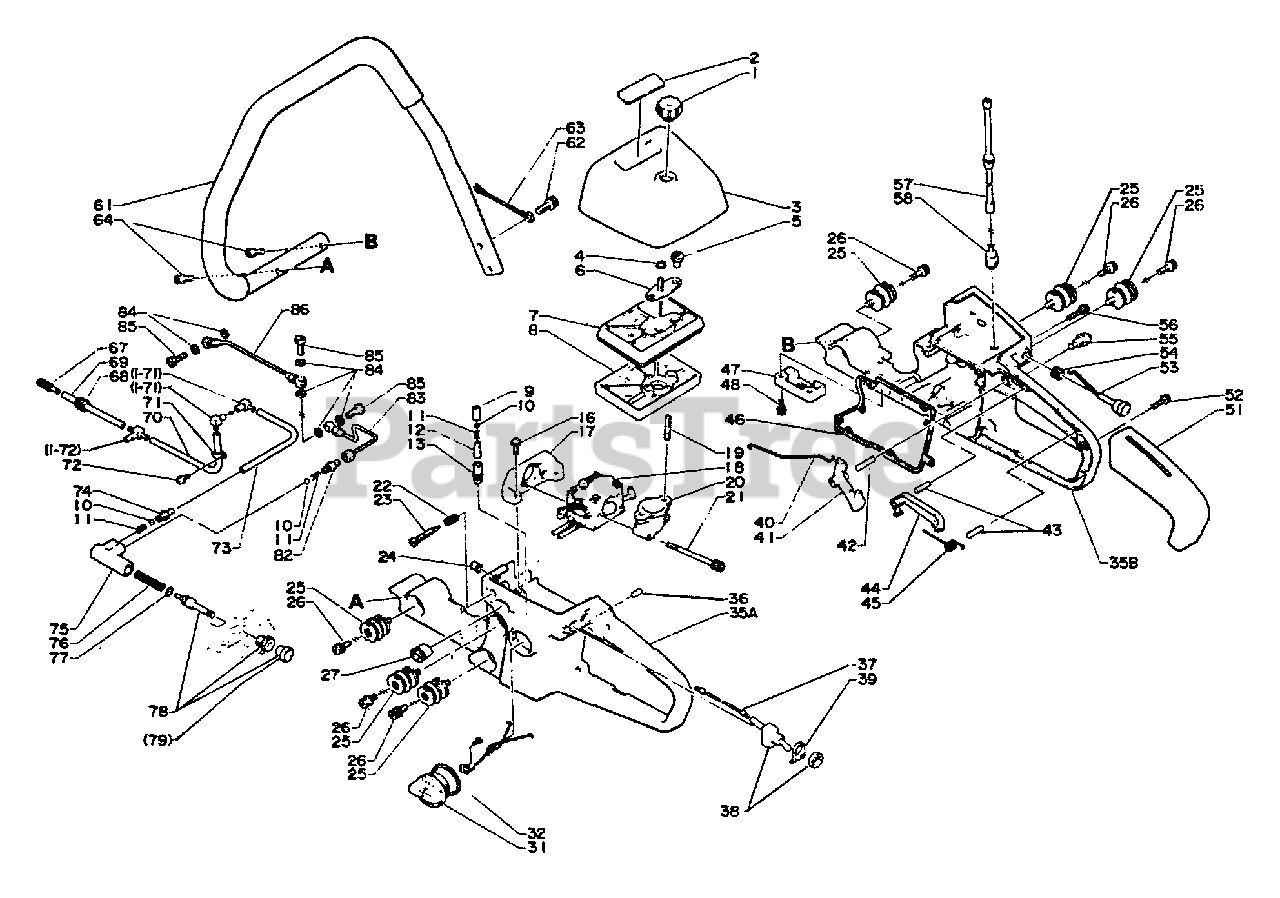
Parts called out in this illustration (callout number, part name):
2	PLATE, MODEL
3	COVER, AIR FILTER
4	RING, RETAINING - 11
9	BREATHER
10	VALVE, BALL
11	SPRING, VALVE
12	BREATHER
13	CONNECTOR
16	SCREW - 5X14
17	CASE, CARBURETOR
18	CARBURETOR
19	STUD
20	PIPE - INTAKE
21	SCREW - 5X75
22	SPRING
23	SCREW, IDLE ADJUST
24	GROMMET
25	CUSHION
26	SCREW - 5X15
27	GROMMET
32	O-RING - 29
35	HANDLE ASSY - REAR
35A	HANDLE ASSY - REAR
35B	HANDLE ASSY - REAR
36	PIN - LOCATING
37	LEAD - GROUND
38	IGNITION SWITCH ASSY
39	LABEL - STOP
40	ROD, THROTTLE
41	TRIGGER, THROTTLE
42	PIN - SPRING -- 5X25
43	PIN - SPRING
44	LOCKOUT, THROTTLE
45	SPRING, LOCKOUT LEVER
46	GASKET, FUEL TANK
47	COVER, PUMP
48	SCREW - 4X12
51	GRIP, HANDLE - REAR
52	SCREW - 4X16
53	ROD, CHOKE
55	LATCH, THROTTLE
56	SCREW - 4X20
57	PIPE - FUEL
58	FILTER, FUEL
61	HANDLE - FRONT
62	SCREW - 6X20
63	LEAD - GROUND
64	SCREW - 5X20
67	FILTER, OIL
69	PIPE - 3X6X220 -- BLACK
70	PIPE - 3X6X130
71	CLIP
72	SCREW - 4X10
73	PIPE - OIL
74	CONNECTOR
75	BODY, OIL PUMP
76	SPRING, OIL PUMP
77	O-RING - 6
78	PISTON, OIL PUMP
79	PUSH BUTTON
82	CONNECTOR
83	PIPE - OIL
85	BOLT
86	PIPE - OIL
